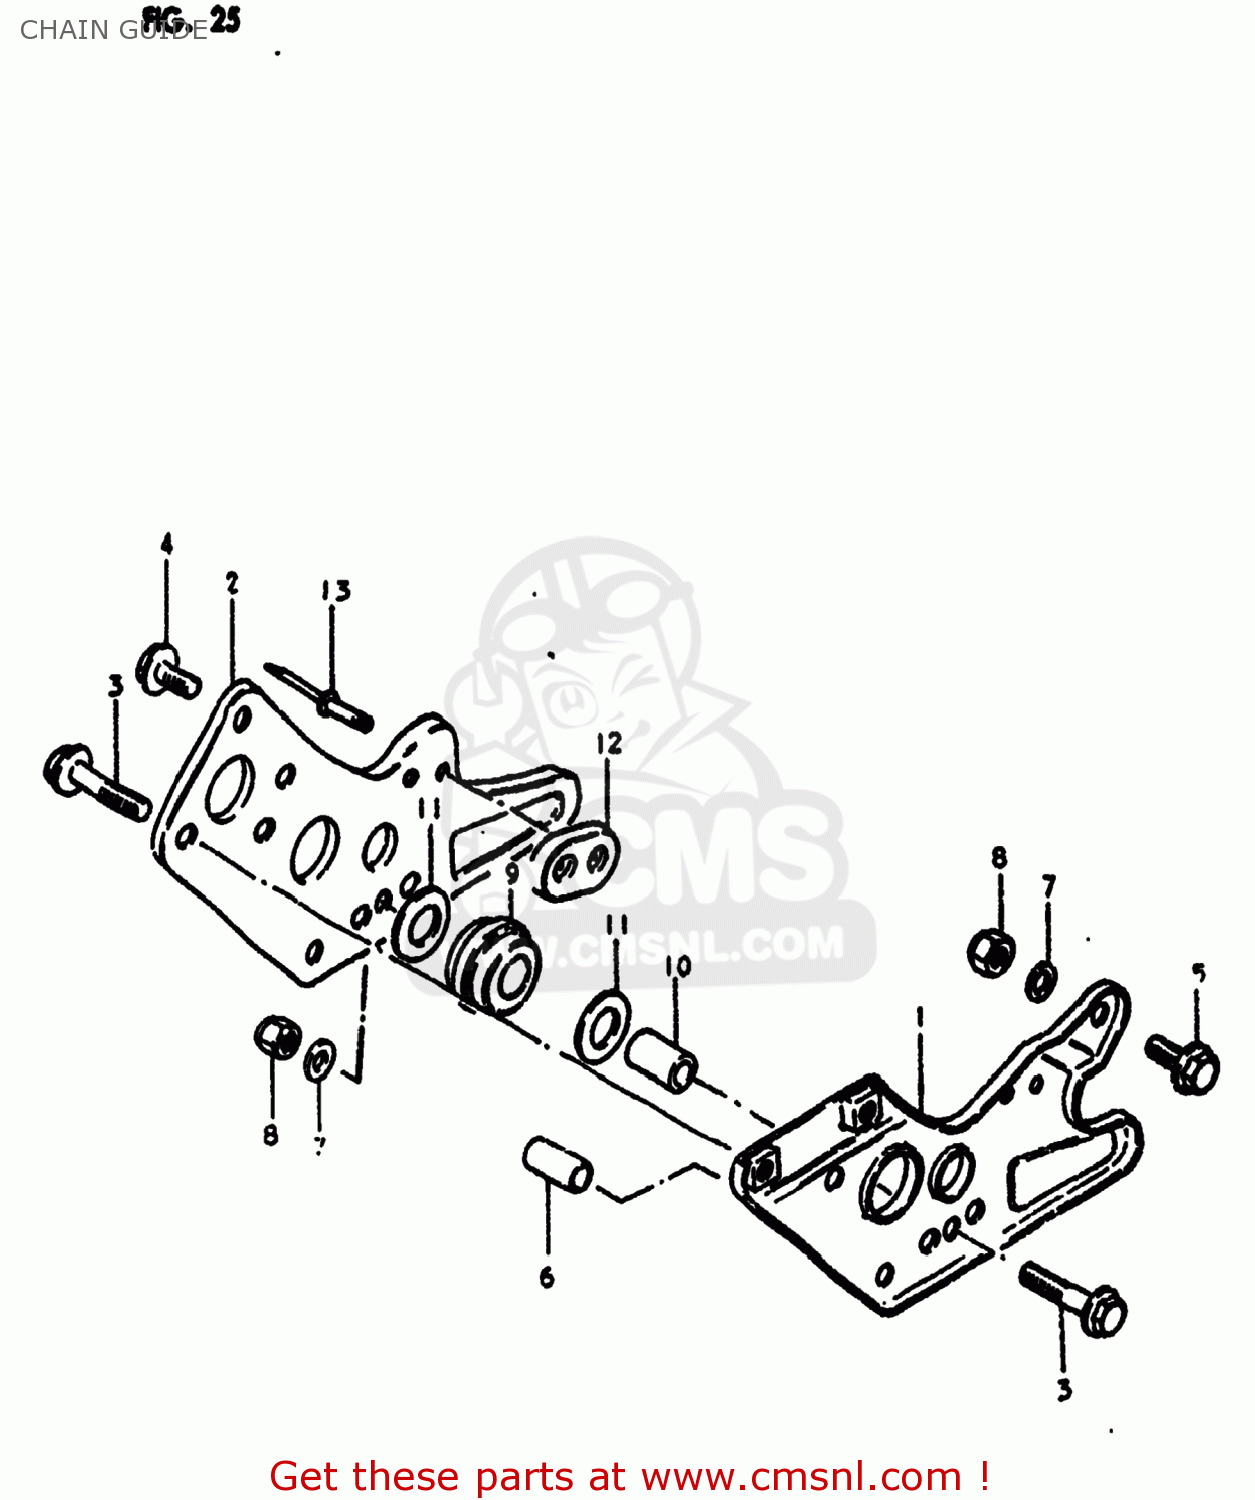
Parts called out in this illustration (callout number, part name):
1	PLATE,CHAIN GUIDE,OUTER
2	PLATE,CHAIN GUIDE,INNER
3	BOLT 6X35
4	BOLT
5	BOLT
6	SPACER(6.8X10X24.2)
7	WASHER
8	NUT 6MM
9	ROLLER,CHAIN GUIDE
10	SPACER,CHAIN GUIDE ROLLER
11	WASHER
12	PAD,DRIVE CHAIN GUIDE
13	RIVET
